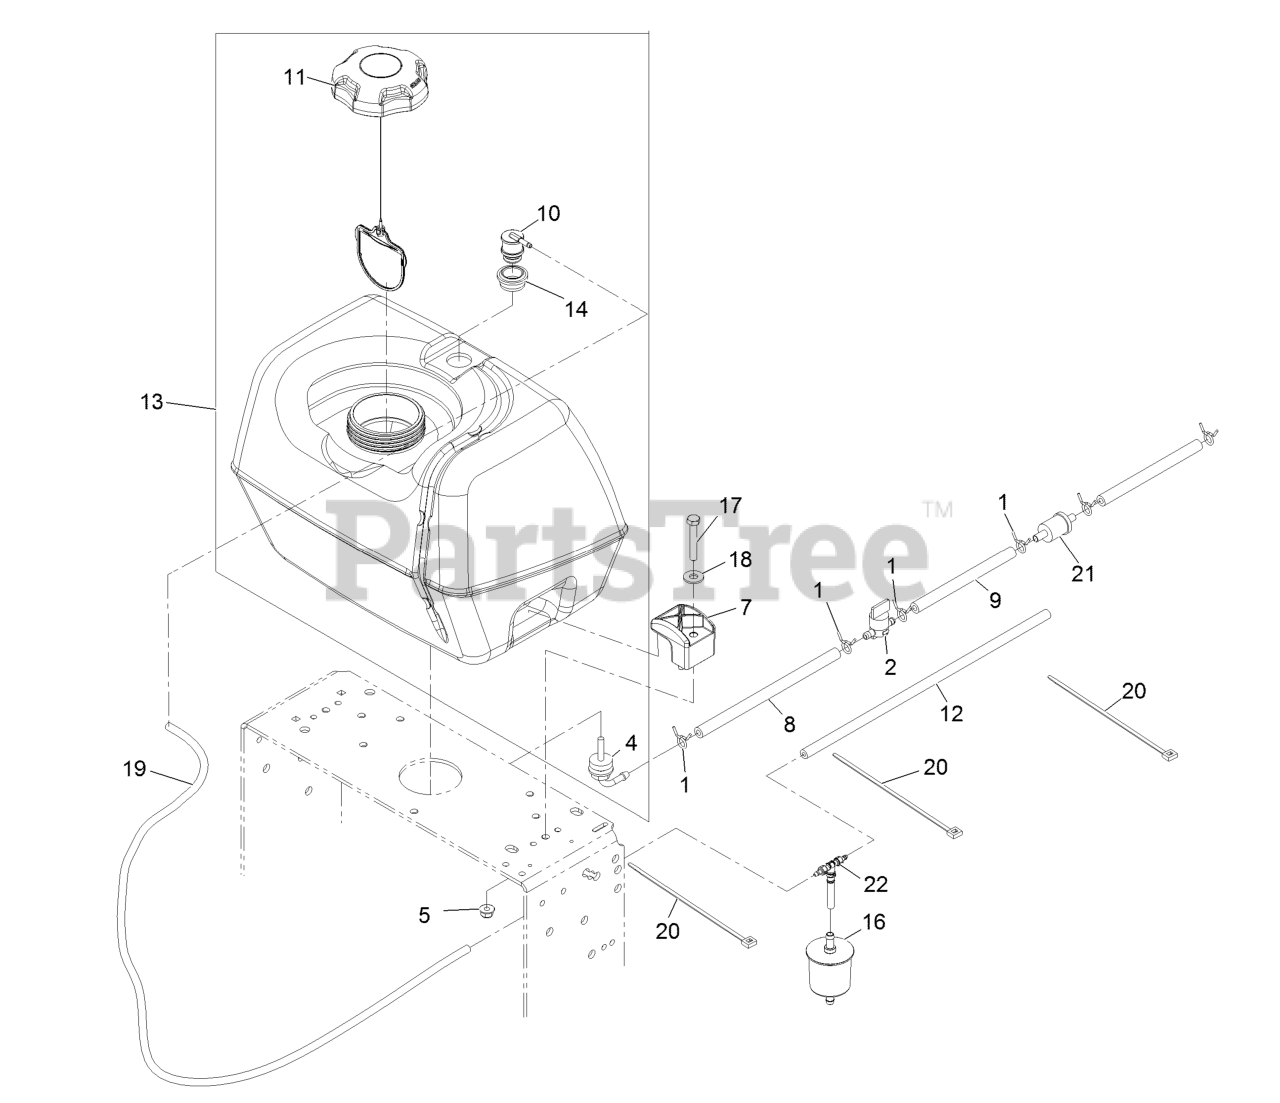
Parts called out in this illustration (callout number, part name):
1	CLAMP-HOSE
2	VALVE-FUEL
4	FITTING-FUEL, BULKHEAD
5	NUT-HF, NI
8	HOSE-FUEL
9	HOSE-FUEL
12	HOSE-FUEL
14	GROMMET
16	FILTER-FUEL
17	SCREW-HH
18	WASHER-FLAT
19	HOSE-EMISSIONS
20	TIE-PLASTIC
21	Pn 41019-1055 Filter W/6in Fuel Line
22	TEE AND CHECK
